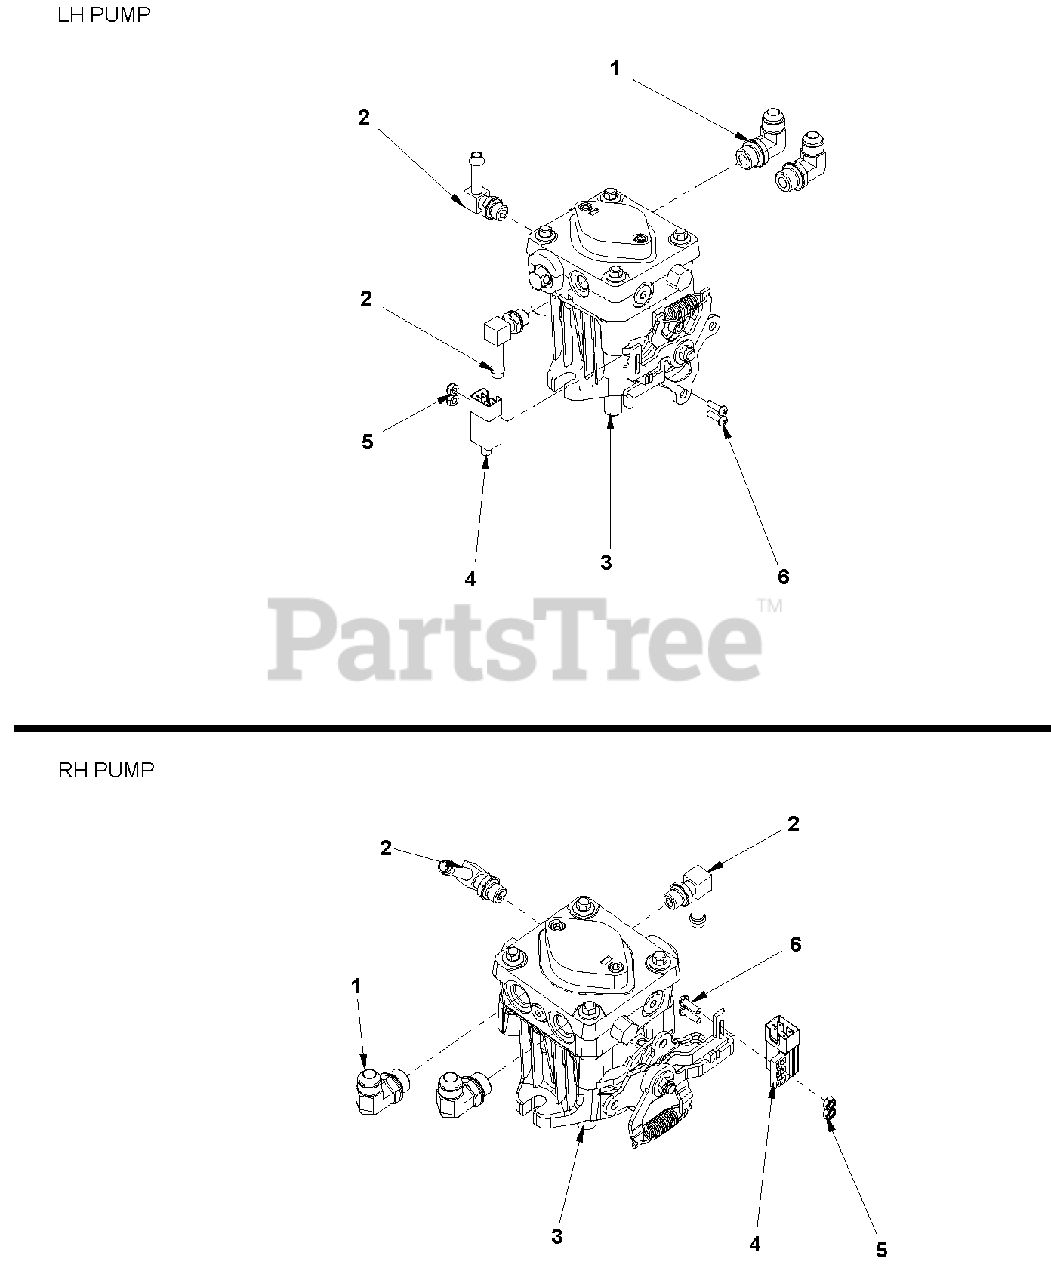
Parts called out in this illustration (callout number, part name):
1	Fitting
2	Fitting, 90 .5625 MOR x .38 HOSE
3	Pump, Hydraulic
4	Switch, Plunger Diametral Pitch
5	Locknut, 10-24 Nyloc
6	Screw, 10-24 x .625 Pan PHL MACY
